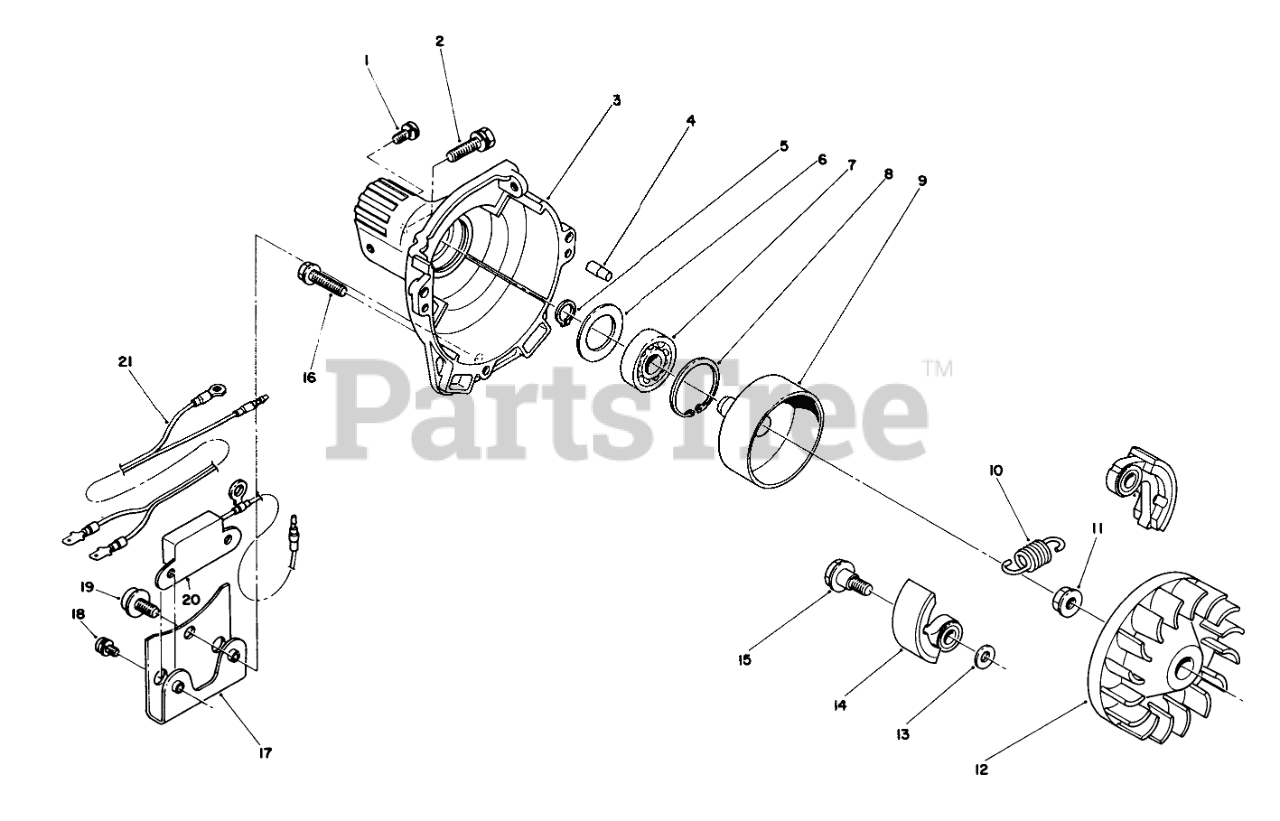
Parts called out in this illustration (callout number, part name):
1	Screw
3	CLUTCH CASE
5	SNAPRING
6	Washer
7	BEARING
8	SNAPRING
9	CLUTCH DRUM
10	Spring
12	Fan
13	Washer
14	SHOE, CLUTCH
15	Bolt-Clutch
16	BOLT & WASHER
17	Bracket-Unit
18	SCREW W/ WASHER
19	SCREW & WASHER
20	Unit-Transistor
21	Wire-Lead
